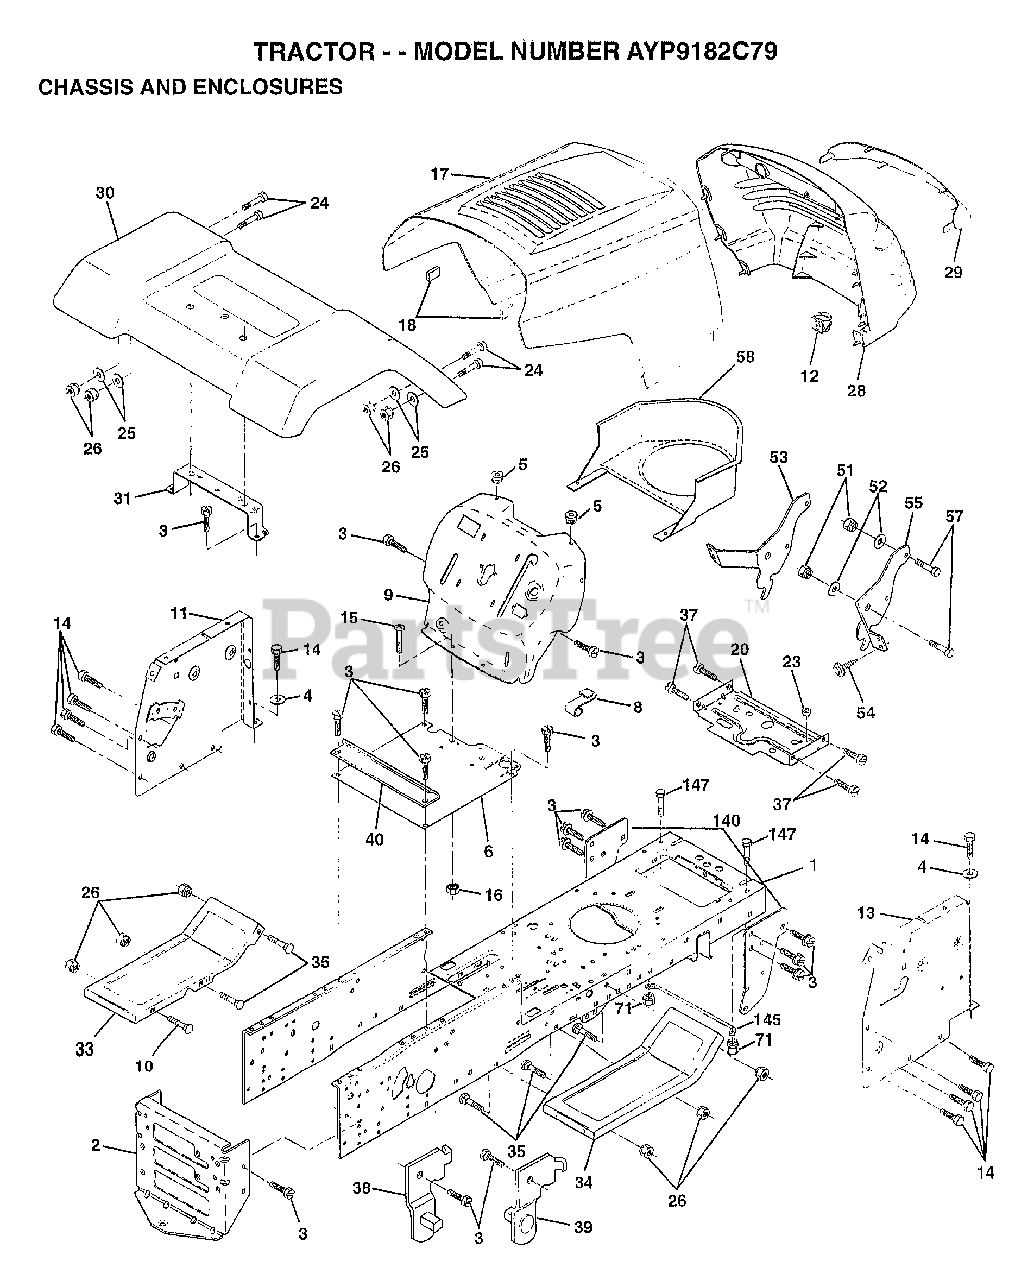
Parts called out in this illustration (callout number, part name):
1	CHASSIS ASM
3	SCREW
4	WASHER
5	BUMPER-HOOD/DASH
6	SADDLE
8	"CLIP,INSULATOR"
9	DASH.SILKSCREENED
11	"PANEL-DASH,LH"
12	CLIP.TINNERMAN
14	SCREW LT
15	SCREW
20	"PLATE-MTG,BATT/FU"
24	BOLT
25	WASHER
26	NUT
28	GRILL.BLK
29	LENS GRILLE
30	FENDER LT
31	BRACKET SUPT FEND
33	FOOTREST LH
34	FOOTREST RH
35	BOLT
37	SCREW LT
38	BRACKET ASM LH
39	BRACKET ASM RH
40	SPACER FENDER LT
51	NUT
52	WASHER
53	BRACKET.GRILLE.LH
55	BRACKET.GRILLE.RH
58	DUCT.AIR.B&S.18HP
140	BRKT SUSPENSION
145	"ROD POVOT,CHASSIS"
147	BOLT LT
